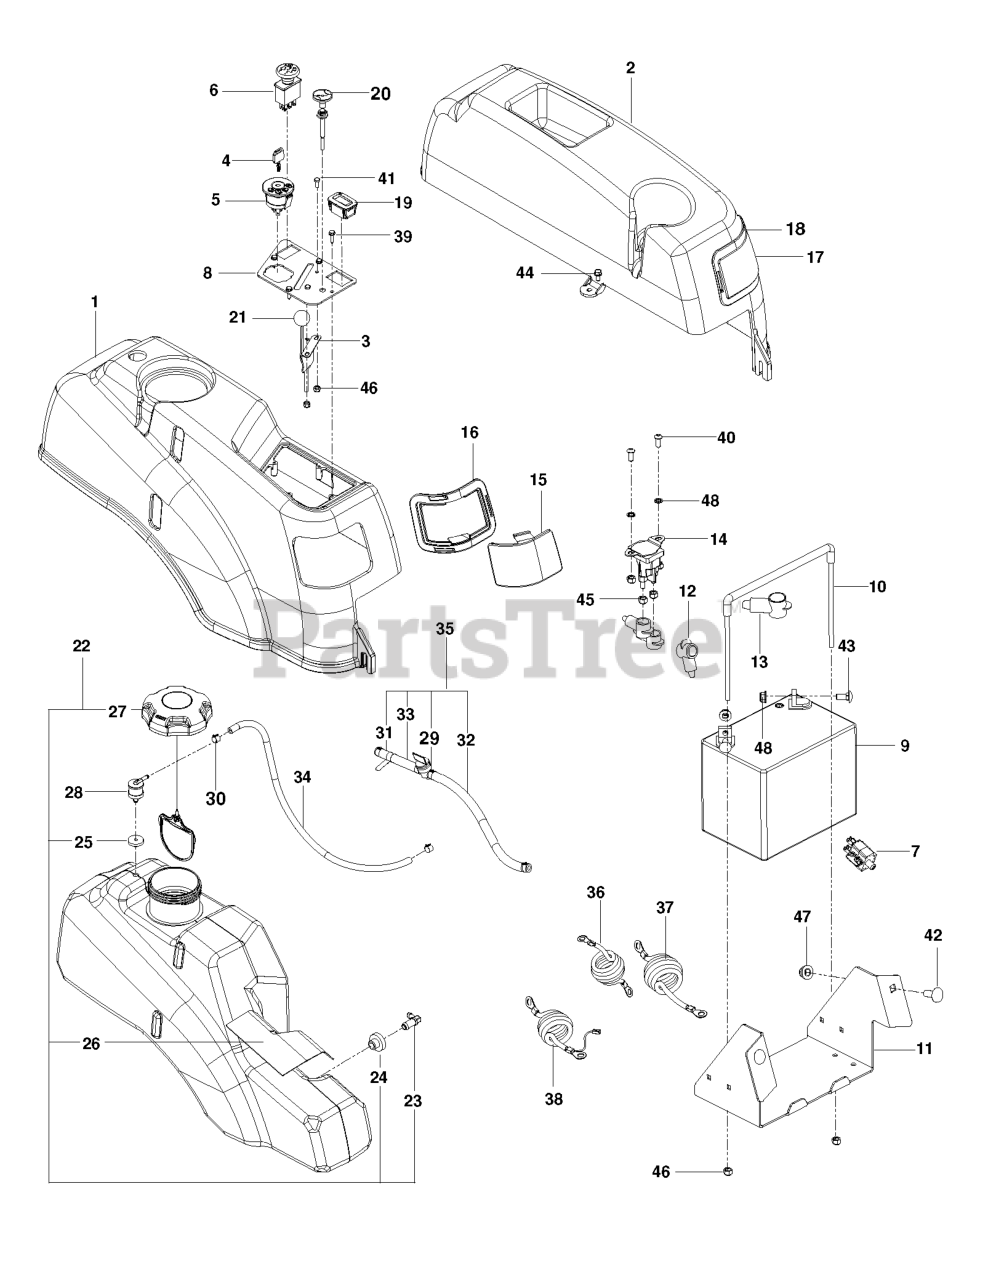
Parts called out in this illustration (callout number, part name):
1	FENDER RT, GRAY
2	FENDER, LT
3	THROTTLE CABLE
4	KEY
5	RP IGNITION SWITCH
6	SWITCH.PTO
7	SWITCH, BRAKE 3P
8	CONSOLE.PLATE
9	BATTERY, 12 V 330 AMP
10	BATTERY TIE DOWN ASSEMBLY
11	BOX, BATTERY, BLACK
12	TERMINAL COVER-SM
15	LENS, COLORED RIGHT
16	RT HEADLIGHT RIM GREY
17	LENS, COLORED LEFT
18	LEFT HEADLIGHT RIM GREY
19	HOUR METER
20	CHOKE CABLE
21	KNOB.ROUND.BALL.BLACK
22	TANK.FUEL.ASSEMBLY.LARGE
23	STEM, FUEL TANK
24	RUBBER GROMMET
25	GROMMET, CHECK VALVE
26	SHIELD, HEAT
27	CAP, FUEL
28	VALVE.FUEL.CHECK
29	FUEL VALVE
30	CLAMP, HOSE
31	HOSE CLAMP
32	GAS LINE 10"
33	FUEL LINE 3"
34	HOSE, VAPOR 3/16 X 15"
35	FUEL LINE ASSY
36	CABLE POSITIVE, LONG
37	BATTERY CABLE, NEGATIVE
38	CABLE POSITIVE LONG W/LEAD
39	HCS #10-24 X 1/2
40	SCR 1/4-20 X 5/8 BTN SKT HD ZD
41	SCR #10-12X3/4 HEX WAS HD ZD
43	RP BOLT 5/16-18 X3/4 ZN/YEL GR
44	BOLT 1/4-20 X 1/2 HWST
45	LOCKNUT.NYLOC.1/4-20
46	NUT 10-24 NYLOC
47	5/16-18 NYLOC FLANGE NUT
48	WASHER 1/4 INT TOOTH
